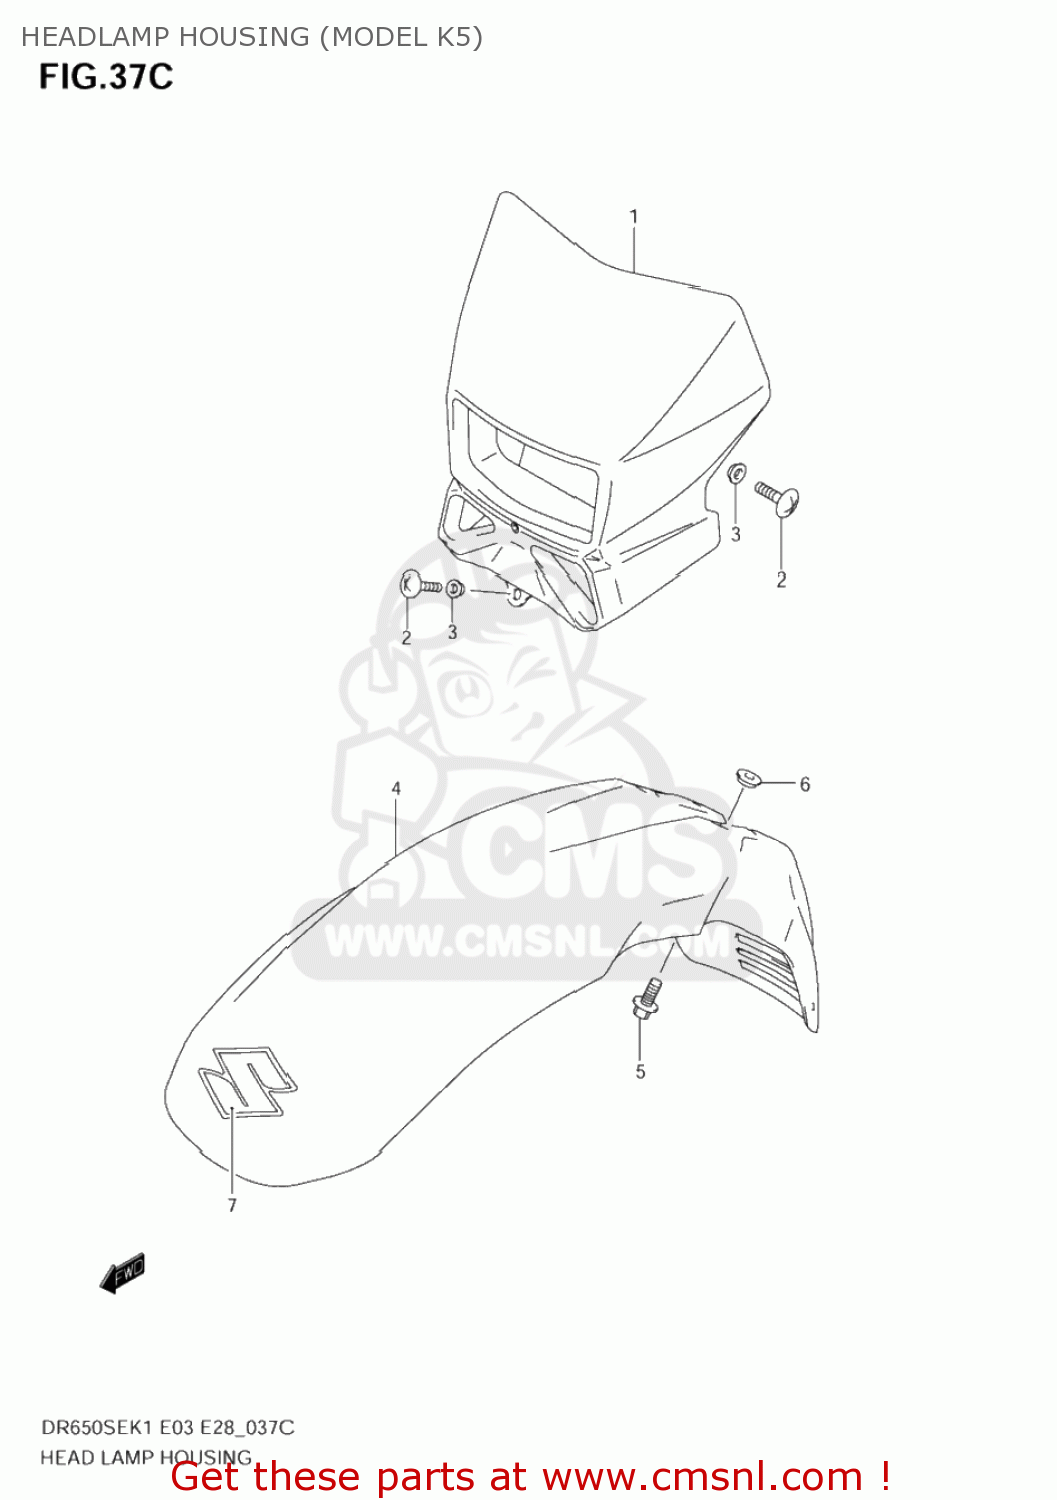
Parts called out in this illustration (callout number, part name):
1	COVER,HEADLAMP
2	SCREW 6X12
3	WASHER
4	FENDER,FR
5	BOLT(6X16)
6	WASHER
7	EMBLEM,S
